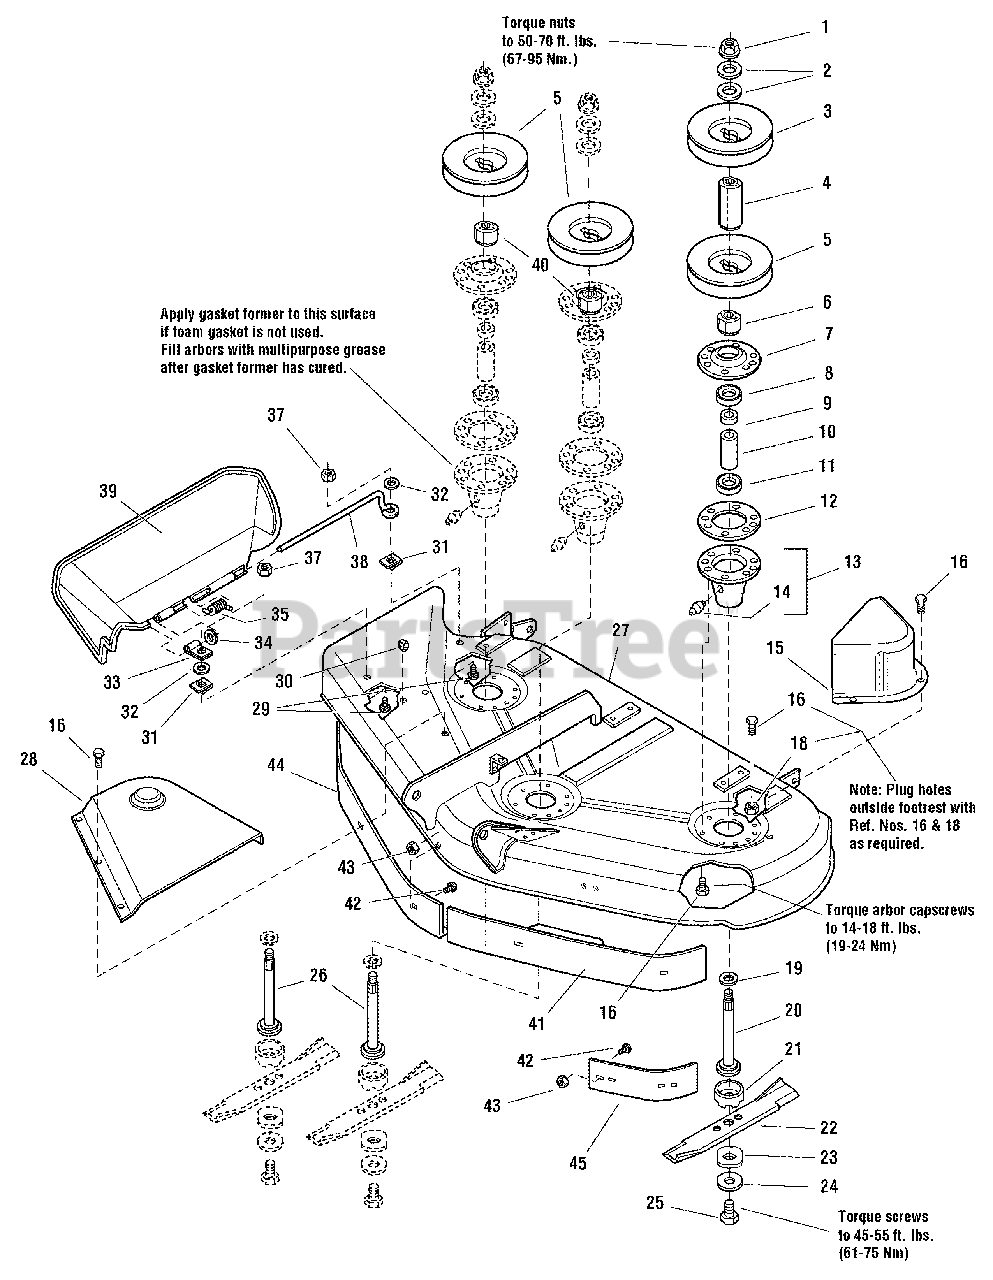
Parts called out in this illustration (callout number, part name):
1	NUT, Hex Flange, 9/16-18
2	WASHER, Bellevilled, 9/16
3	PULLEY, 4-1/2 O.D.
3	PULLEY, 5 O.D.
4	HUB, Double Pulley
5	PULLEY
6	HUB, Double Pulley
7	COVER, Arbor Housing
8	BEARING, Ball, 3/4 x 1-3/4 x 5/8
9	SPACER, 21/32 x 3/4 x 5/8
10	SPACER, 11/16 x 5/32 x 2-11/16
11	BEARING, Ball, 11/16 x 1-9/16 x 15/32
12	GASKET, Foam
13	HOUSING ASSEMBLY, Arbor Bottom, w/Lube Fitting
14	FITTING, Grease
15	COVER, Arbor
15	COVER, Arbor without Ribs
16	CAPSCREW, Hex Head Taptite, 5/16-18 x 3/4
18	NUT, Hex Flange, 5/16,
19	WASHER, Bellevilled, 9/16, Black
20	SHAFT, Arbor (LH)
21	SHIELD, Grass, Lower
22	BLADE, Mower, 16-1/8
23	WASHER, Hex, 11/16 x 2
24	WASHER, Spring 15/32, Black
25	CAPSCREW, Hex Head, 7/16-14 x 1
26	SHAFT, Arbor (Center & RH)
27	MOWER HOUSING ASSEMBLY, 44" Mower (Orange)
27	MOWER HOUSING ASSEMBLY, 44" Mower (Red)
28	COVER, Arbor
29	CARRIAGE BOLT, 1/4-20 x 7/8
30	PLUG, Hole
31	NUT, Push
32	WASHER, 1/4, Black
33	CLAMP
34	WASHER, 5/16, Black
35	SPRING
37	NUT, ESNA 1/4-20
38	ROD, Deflector, Front
39	DEFLECTOR, Plastic
40	HUB, Pulley, Center & RH
41	BAFFLE, Anti-Blowout, LH
42	CARRIAGE BOLT, 5/16-18 x 3/4, Black
43	NUT, Hex Flange Whiz Lock, 5/16-18, Black
44	BAFFLE, Anti-Blowout, RH
45	BAFFLE, Blowout, 44" & 50"
